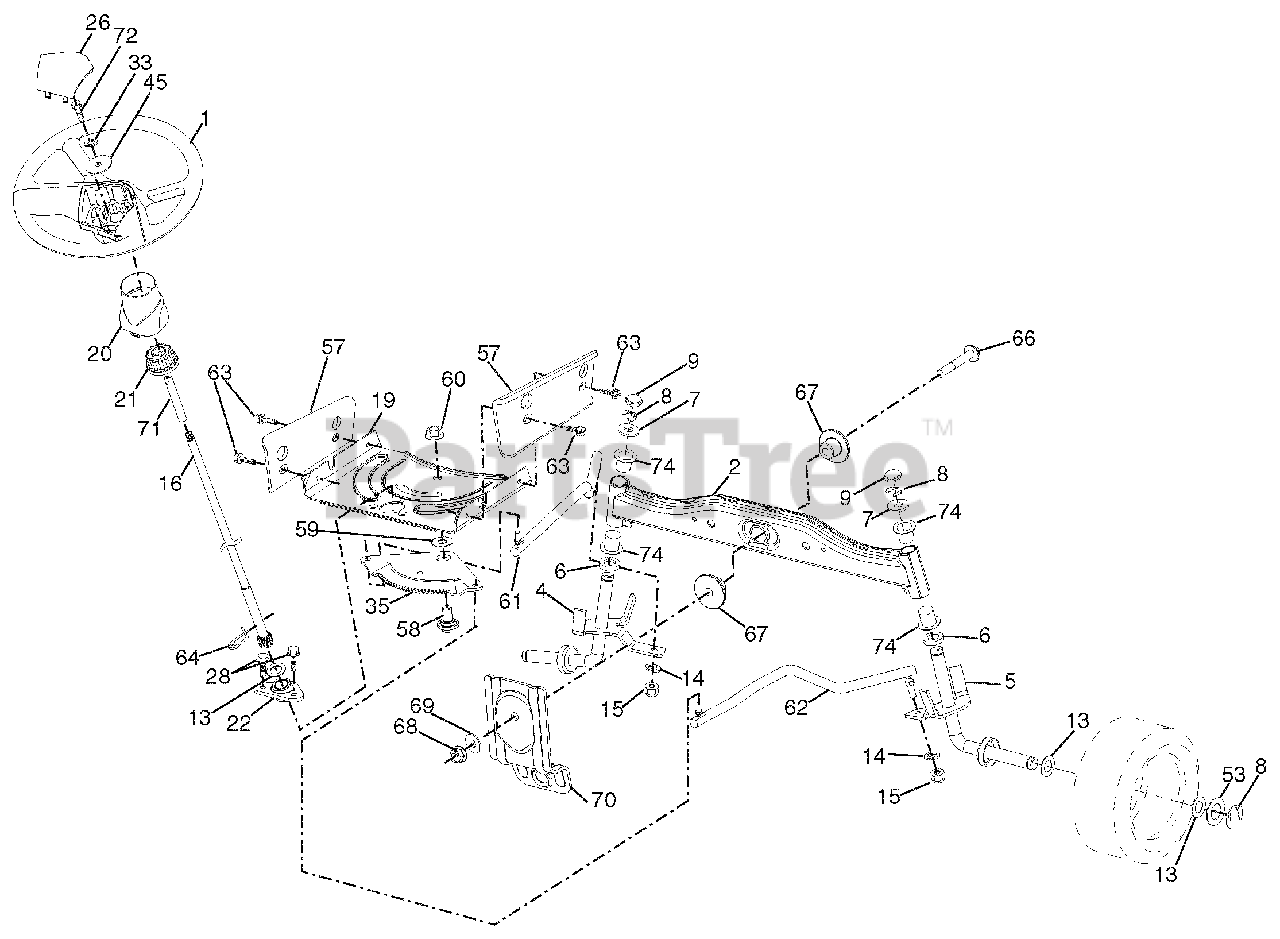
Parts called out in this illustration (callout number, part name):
1	WHEEL.STEERING.HARD RIM.BLACK
2	AXLE ASM.WELDED
4	SPINDLE.WELDED.LH.15"TEX
5	SPINDLE.WELDED.RH.15"TEX
6	WASHER.THRUST..75 X 1.230
7	WASHER.25/32 X 1-5/8 X 16GA.
8	RING.KLIP.#T5304-75
9	CAP.SPINDLE.FR.TOP.BLK.
13	WASHER.25/32 X 1 1/4 X 16 GA.
14	Washer, Lock 3/8
15	NUT.CROWNLOCK.3/8-24
16	SHAFT.STEER.5/8 TEX.NON-PLATED
19	PLATE.STEER.DDL.NLT/NGT
20	BOOT.STEERING.LT.TEX P/L.428
21	ADAPTER.WHEEL.STRG..760
22	BUSHING ASM STEERING.ALUM.NLT
26	CAP.WHL.STRG.HRS/SRS.BLACK
28	SCREW.HEXWSH THDR3/8-16X3/4.BL
33	Washer, Lock 5/16
35	GEAR SECTOR.PLATE.DDL.NLT/NGT
45	WASHER.11/32ID X2 3/8OD X 12GA
53	WASHER.HARDEN..793 X 1.637X060
57	BRACKET.UPSTOP.TEX
58	BOLT.SHOULDER.SECTOR.PIVOT.CFM
59	WASHER.THRUST.SECTOR.STEER.NLT
60	NUT.FLANGE LOCK.5/8-11
61	DRAGLINK.LH.BALLSTUD.DDL.
62	DRAGLINK.RH.BALLSTUD.DDL
63	SCREW.5/16-18X3/4.SMGML.TAP/BL
64	RETAINER.CLIP.SPRING.STEERING
66	BOLT.HEX.FGHD.7/16-14 X 3.SERR
67	BUSHING.PM.FRONT AXLE
68	NUT.LOCK.FLANGE.7/16-14.GR5
69	WASHER.1.5 X .505 X .118
70	BRACKET.DECK.SUSPENSION.FRONT
71	SHAFT.EXTEN.STRG.SPLINE.TEX
72	BOLT.FIN.HEX.5/16-18UNCX4.5.G5
74	BEARING.COL.STRG.BLK.
